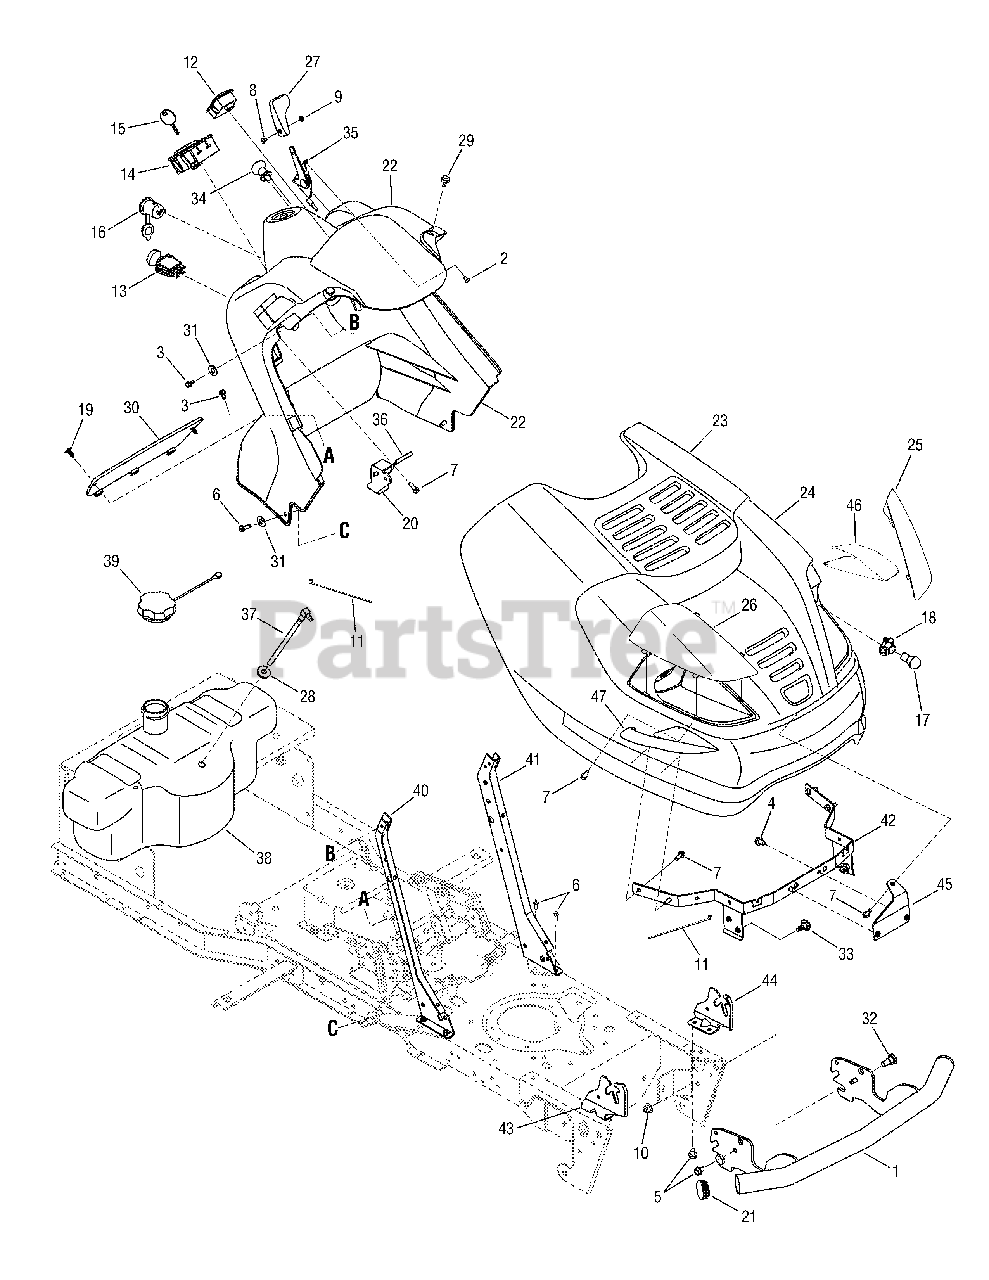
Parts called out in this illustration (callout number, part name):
2	Screw, Truss Hd. Mach., 10-24 x .375
3	Screw, Hex Wash Hd. Tapp, 1/4-20 x .5
4	Screw, Hex Wash Hd. Tapp, 5/16-18 x .625
5	Screw, Hex Wash Hd. Tapp, 5/16-18 x .5
6	Screw, Hex Wash Hd. Tapp, 1/4-20 x .75
7	Screw, Hex Wash Hd. Tapp, 1/4-15 x .75
8	Screw, Truss Hd. Mach., #8-32 x .375
9	Nut, Hex, 8-32
10	Nut, Hex Flange Insert Lock, 3/8-16 GrF
11	Tie, Cable
12	Meter, Indicator/Service Monitor
13	Switch, PTO
14	Switch, Ingition/Module
15	Key, Ignition Switch
16	Receptacle, 12V Power
16	Plug, Button
17	Bulb, 12V Light
18	Receptacle, Light
19	Clip, Ratchet
20	Lever, Dash Brake
21	Cap, Bumper
22	Panel, Dash
24	Plenum, Hood
25	Lense, Head Light LH
26	Lense, Head Light RH
27	Knob, Throttle Control
28	Bushing, Fuel Tank
30	Net, Storage
31	Washer, Flat, .25 x .63 x .0515
32	Bolt, Shoulder, .496 x .336:3/8-16
33	Screw, Shoulder, .43 x .29:TT5/16-18
34	Cable, Choke Control
35	Cable, Throttle Control
36	Rod, Brake Lock Pivot
37	Fitting, Fuel Pick Up
38	Tank, Fuel
39	Cap, Fuel Tank
47	Label, Reflector
